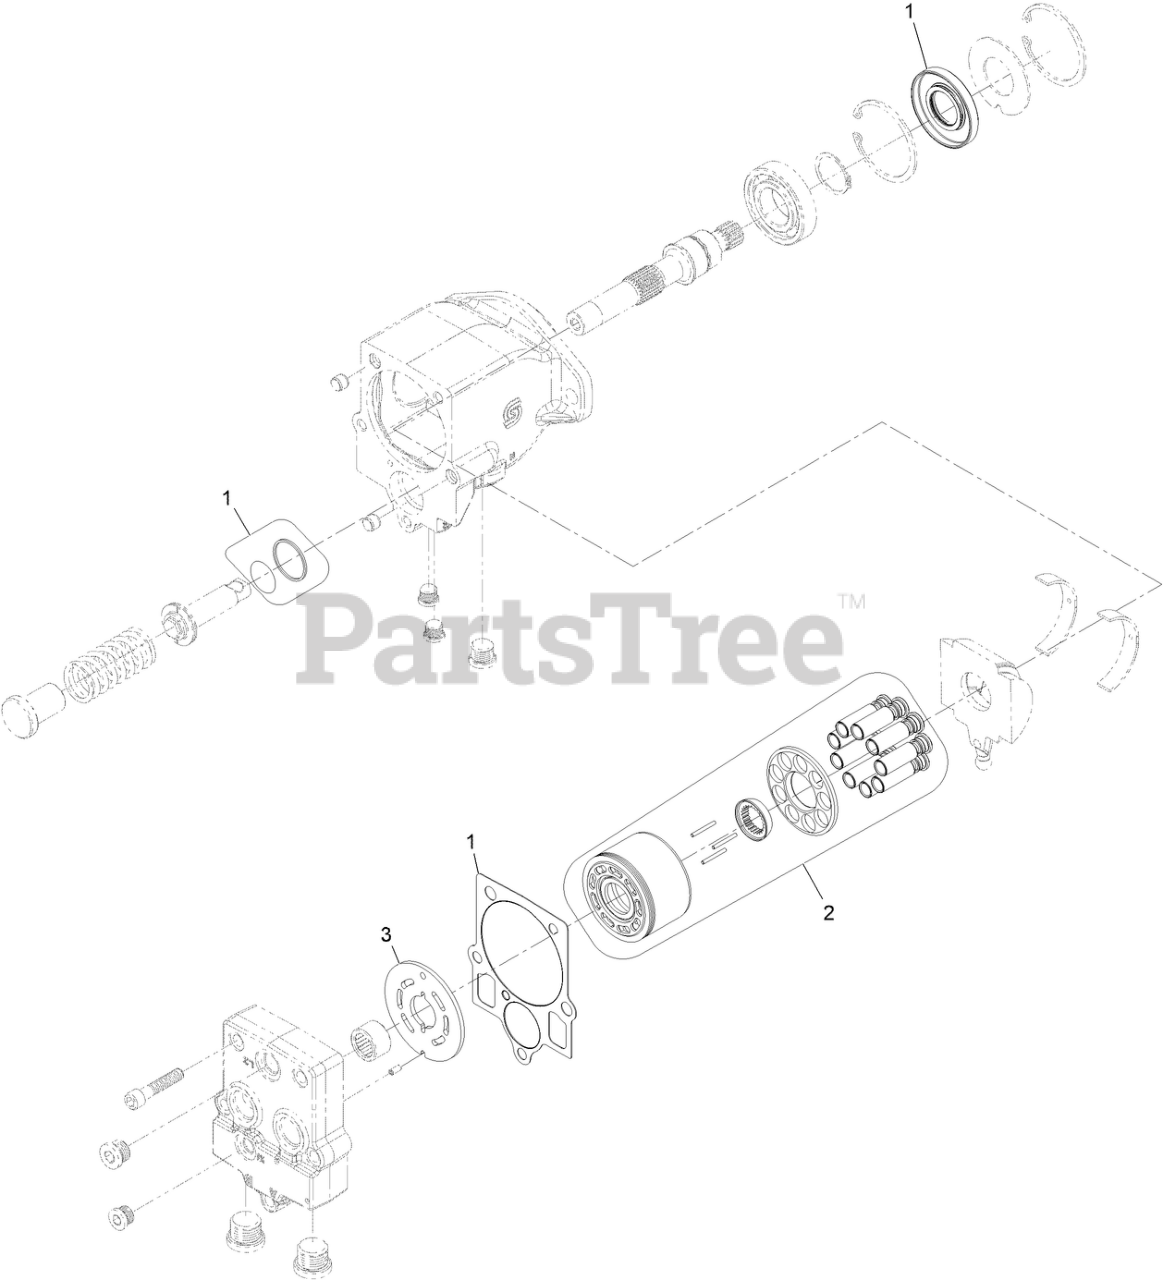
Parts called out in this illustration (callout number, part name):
1	OVERHAUL SEAL KIT
2	CYLINDER BLOCK KIT
3	PLATE-VALVE
